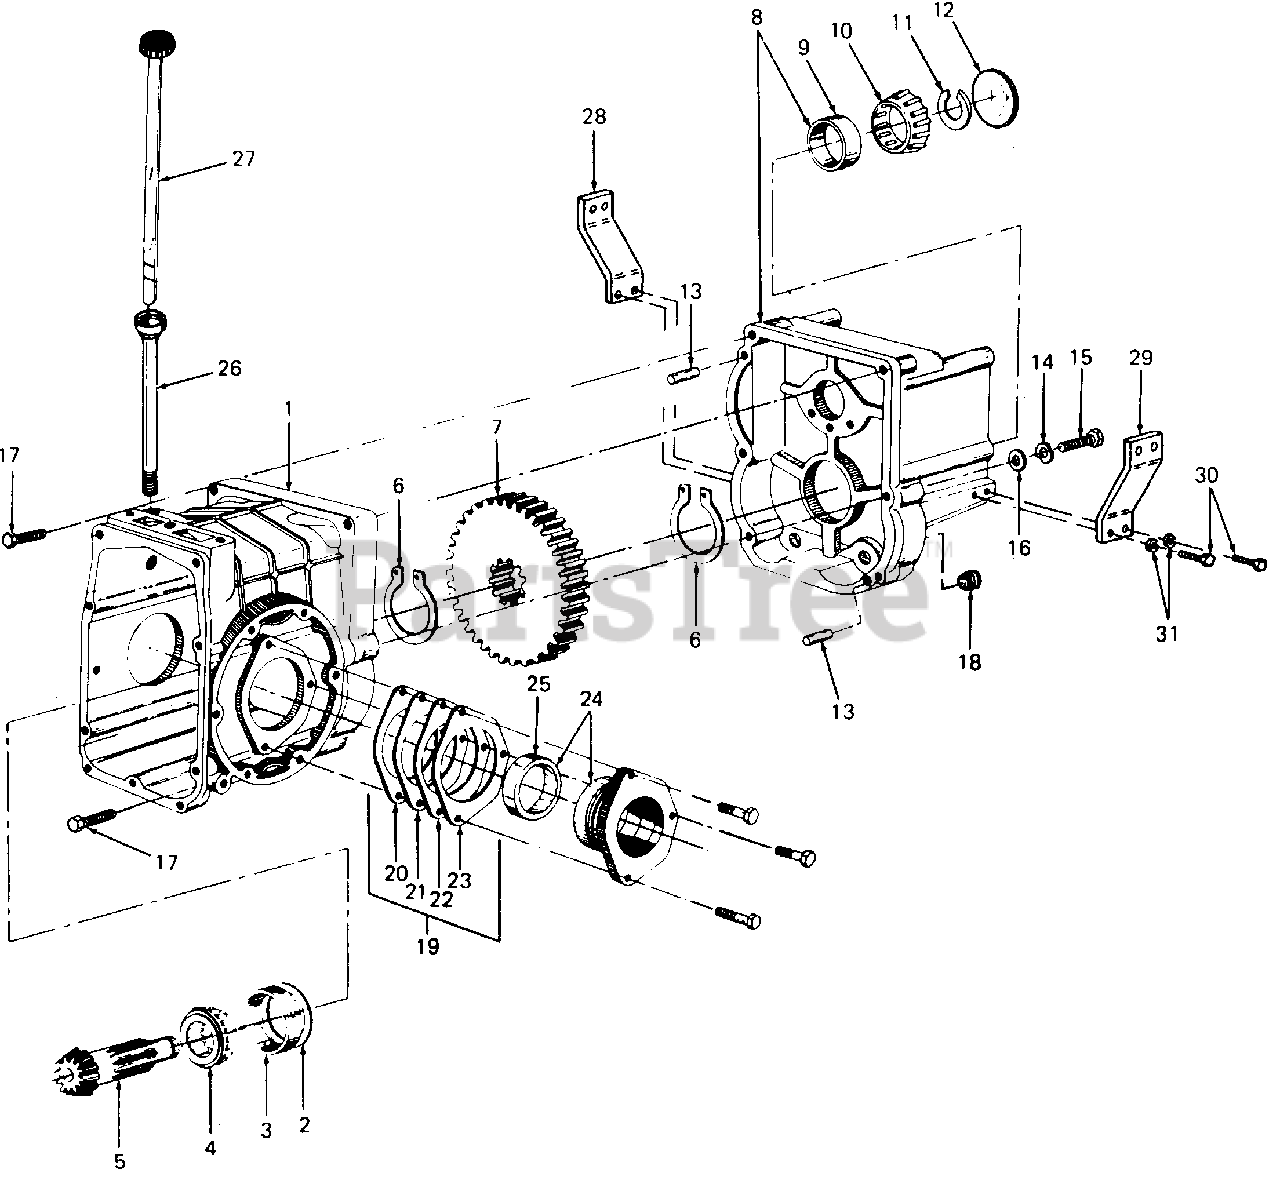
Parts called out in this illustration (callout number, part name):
1	Housing Assy, Rear Transaxle
2	Shim, Rear Bearing Cup, .004 Thk
3	Cup, Roller Bearing
4	Cone, Roller Bearing
5	Shaft, Bevel Pinion
6	Ring, Retaining, 1.312 Dia
7	Gear, Reduction - 68T
8	Housing Assy, Adapter w/Cup
9	Cup, Roller Bearing
10	Cone, Roller Bearing
11	Retainer, Front Bearing, .125 Thk
12	Plug, Expansion, 2.12 OD
13	Pin, Dowel, 3/8 Dia X 5/8 Lg
14	Washer, Spring, .445 X .75 X .017 Thk
15	Screw, Hex Cap, 7/16-14 X 2.5 Lg GR5
16	Washer, Flat, .46 X .875 X .060 Thk
17	Bolt, Hex Patch, 7/16-14 X 1.75 Lg GR5
18	Plug, Drain
19	Shim Package
20	Shim, Bearing Retainer, .004 Thk
21	Shim, Bearing Retainer, .007 Thk
22	Shim, Bearing Retainer, .014 Thk
23	Shim, Bearing Retainer, .028 Thk
24	Retainer Assy, Bearing w/Cup
25	Cup, Roller Bearing
26	Tube, Dipstick
27	Blade Assy, Dipstick
28	Bracket, Trans Mtg - LH
29	Bracket, Trans Mtg - RH
30	Bolt, Hex Patch, 3/8-16 X 1.0 Lg GR5
31	Washer, Lock, 3/8
